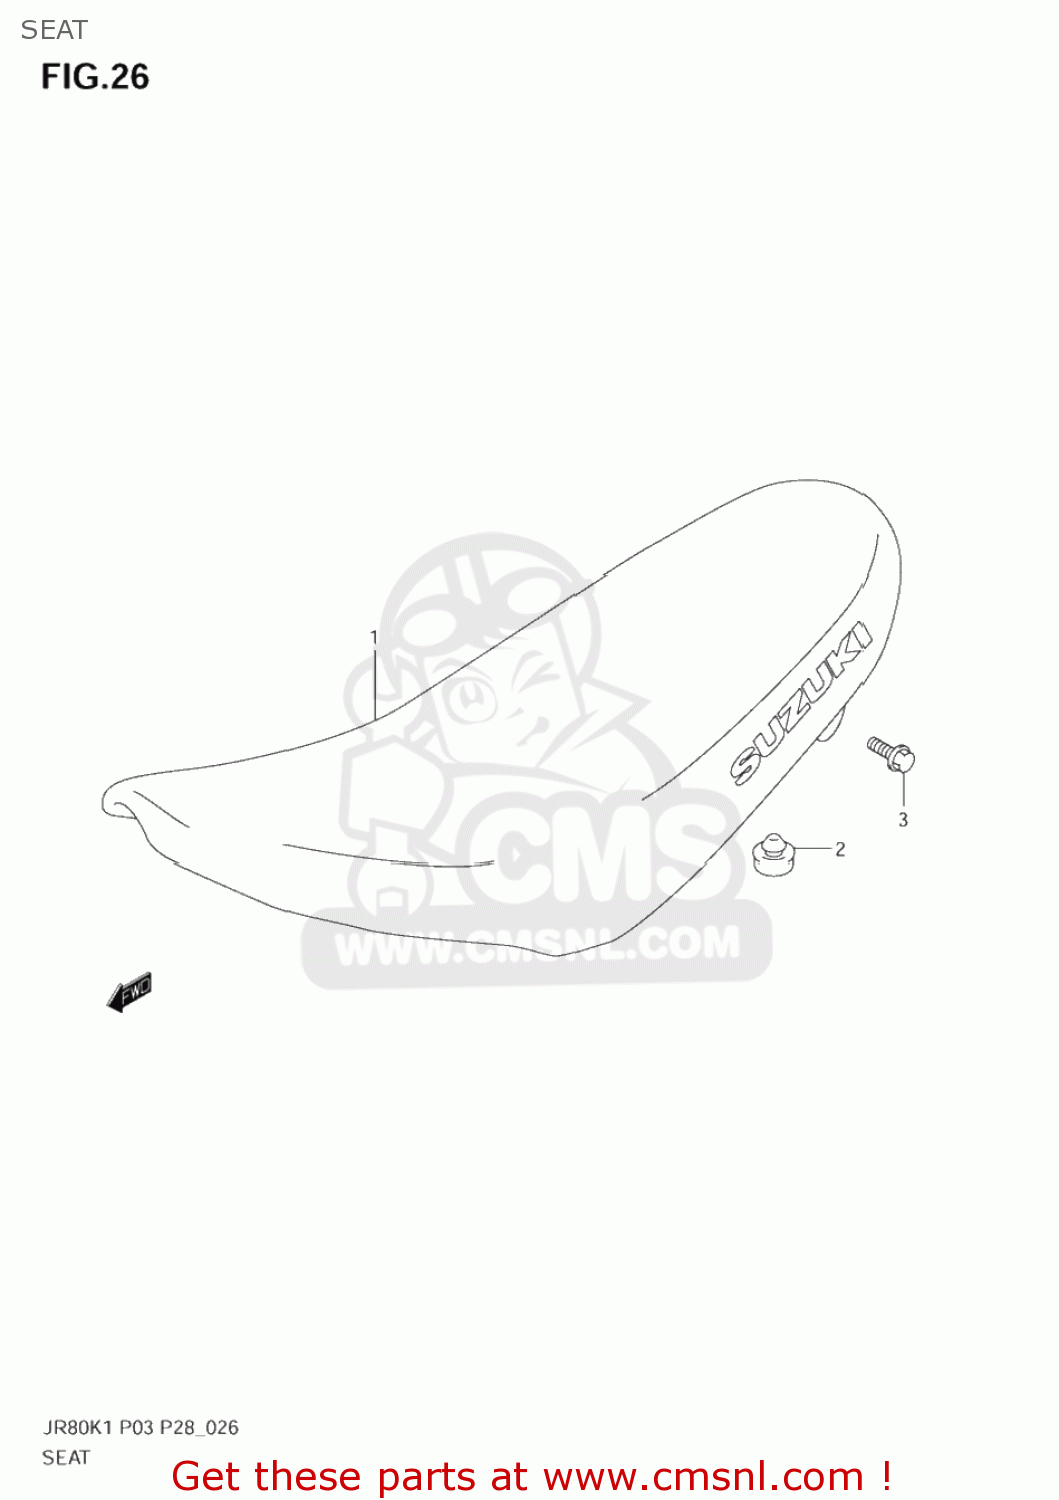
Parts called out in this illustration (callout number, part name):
1	SEAT ASSY
2	CUSHION
3	BOLT
